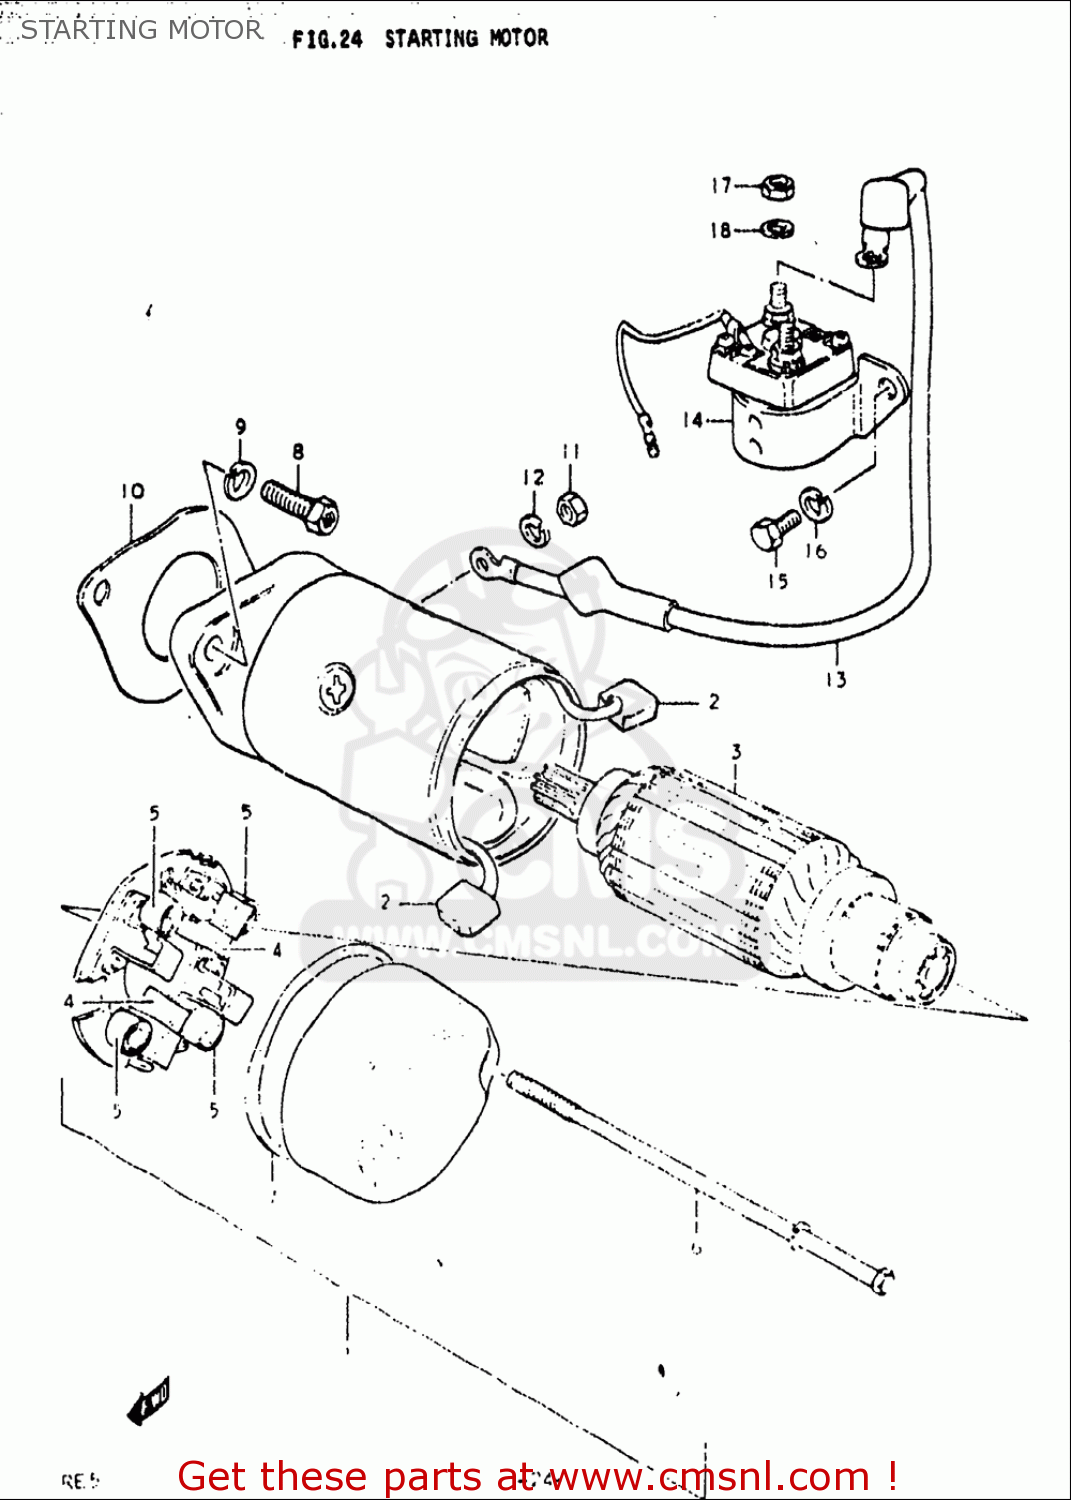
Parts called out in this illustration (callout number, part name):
8	BOLT
9	WASHER,LOCK
11	NUT
12	WASHER,LOCK
14	RELAY ASSY,STARTING MOTOR
15	BOLT(6X8)
16	WASHER,LOCK
17	NUT
18	WASHER,LOCK
